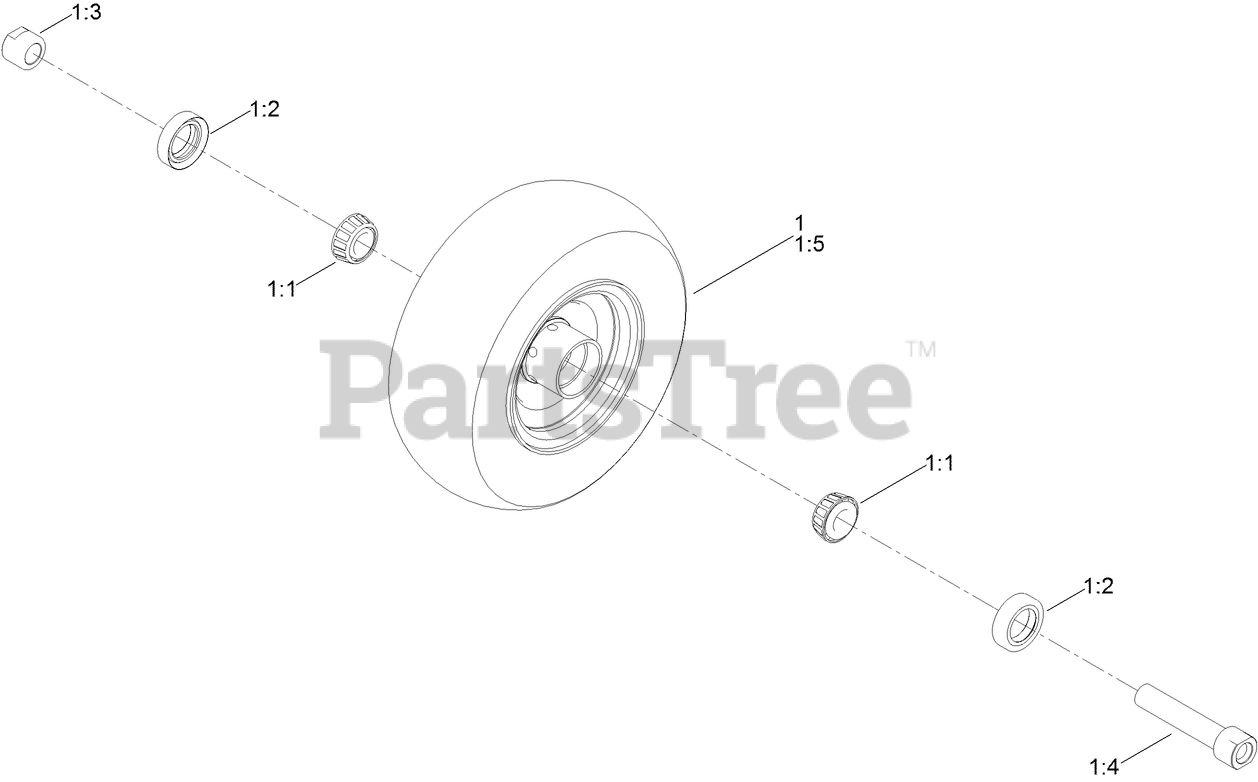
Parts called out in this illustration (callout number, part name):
1	WHEEL AND BEARING ASM
1:1	BEARING-CONE, TAPER
1:2	SEAL-CASTER
1:3	SPACER-NUT
1:4	CASTER AXLE ASM
1:5	WHEEL AND TIRE ASM
